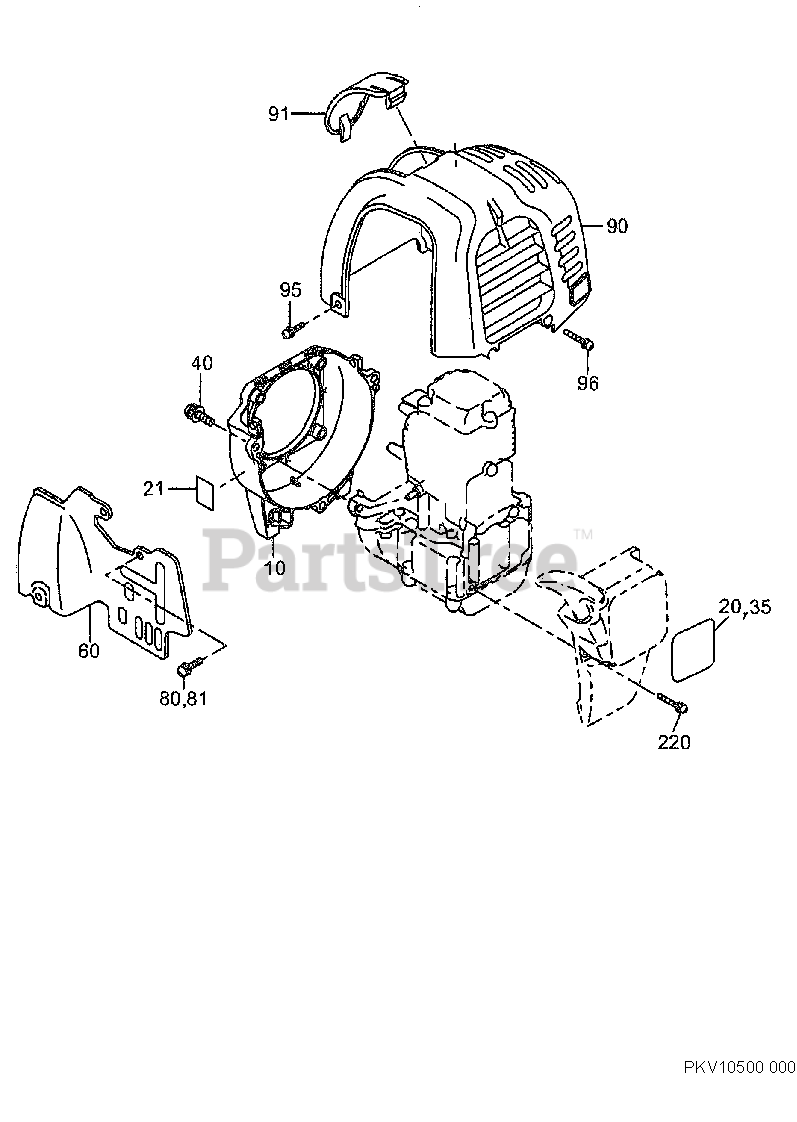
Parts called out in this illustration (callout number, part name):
10	BLOWER HOUSING
21	LABEL, TRADEMARK
35	LABEL, ENGINE
40	SCREW AND WASHER AY
60	INSULATOR, CARBURETOR
80	SCREW AND WASHER AY
81	SCREW AND WASHER AY
90	COVER, CYLINDER
95	SCREW AND WASHER AY
